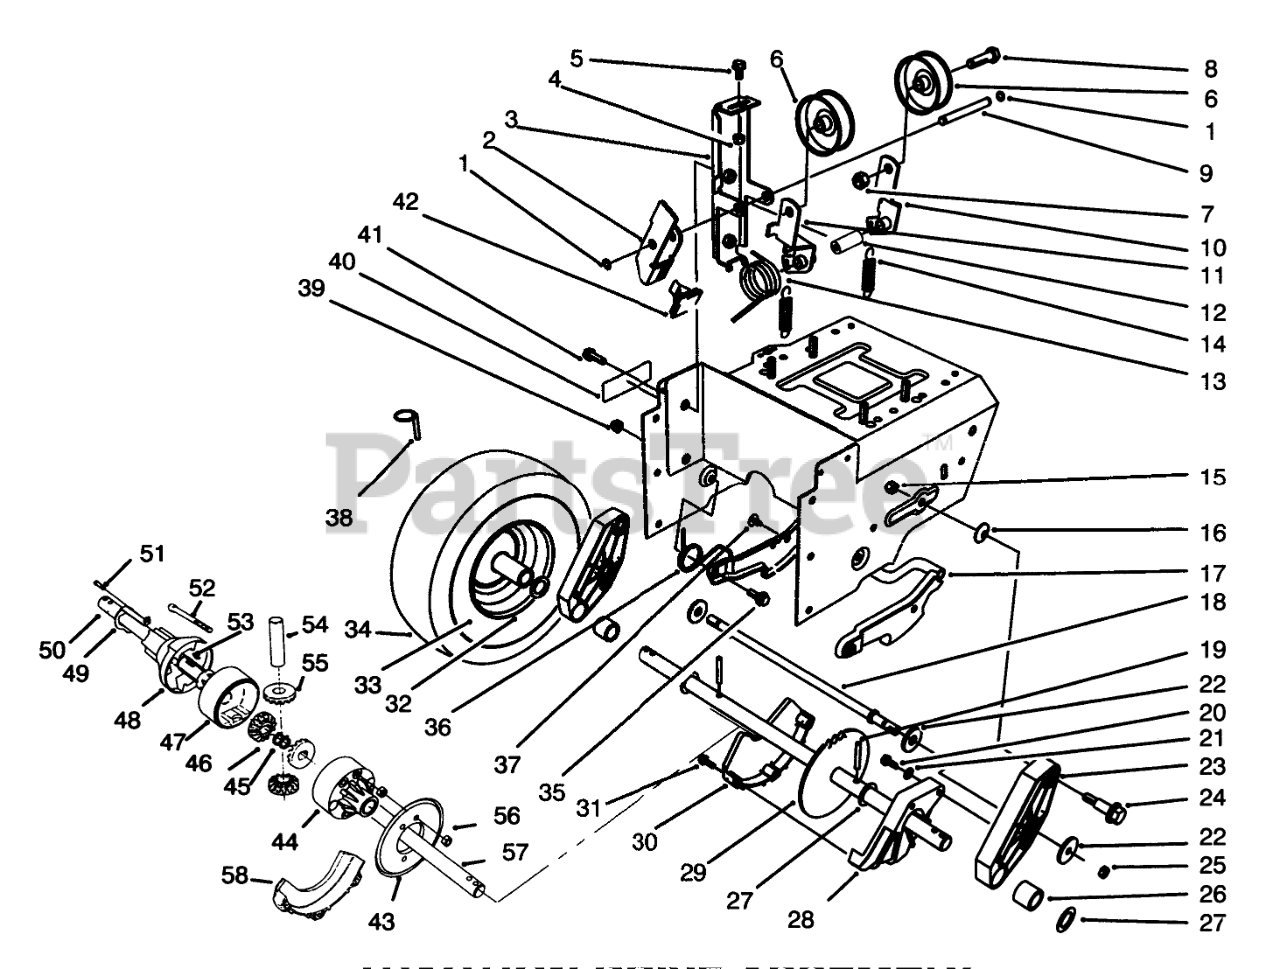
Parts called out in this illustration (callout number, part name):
1	RING-RETAINING
2	ARM-BRAKE
3	IDLER ARM BRACKET ASM
4	NUT-LOCK, NI
5	SCREW-HHF
6	PULLEY-IDLER
7	NUT-LOCK, NI
8	SCREW-HH
9	PIN-IDLER
10	TRACTION IDLER ARM ASM
11	IMPELLER IDLER ARM ASM
12	WASHER-FLAT
13	TORSION SPRING
14	SPRING-EXTENSION
15	NUT-LOCK, NI
16	WASHER-SPRING
17	Latch-Arm
18	ROD-LATCH
19	PIN-ROLL, SLOTTED
20	SCREW-HWH
21	WASHER-FLAT
22	WASHER-SUPPORT
23	Pivot-Arm Assembly (Incl. Ref. # 26)
24	BOLT-SHOULDER
25	NUT-LOCK, NI
26	BUSHING-AXLE
27	WASHER-THRUST
28	GUARD-CHAIN, LH
30	GUARD-CHAIN, RH
31	Screw
32	RIM-WHEEL
33	INNER TUBE
35	SCREW-SHOULDER
36	SPRING-LATCH, TORSION
37	FASTENER-PANEL
38	PIN-LYNCH
39	NUT-LOCK, NI
40	DECAL-WARNING
41	SCREW-HHF
42	PAD-BRAKE
43	SPROCKET, 32 T
44	DIFFERENTIAL ASM
45	RING-RETAINING
46	Gear-Side Pinion (Model 38590 Only)
47	HOUSING ASSY - MALE
48	COUPLING-DIFFERENTIAL
49	SPRING-LOCKOUT
50	SHAFT - DIFFERENTIAL,RH
51	Screw-Hex. Washer Hd (Model 38590 Only)
52	Screw-Hex. Hd. (Model 38590 Only)
53	KEY-WOODRUFF
54	Shaft-Cross (Model 38590 Only)
55	Gear-Cross Shaft (Model 38590 Only)
56	NUT-LOCK, NI
57	SHAFT - DIFFERENTIAL,LH
58	GUARD-CHAIN
